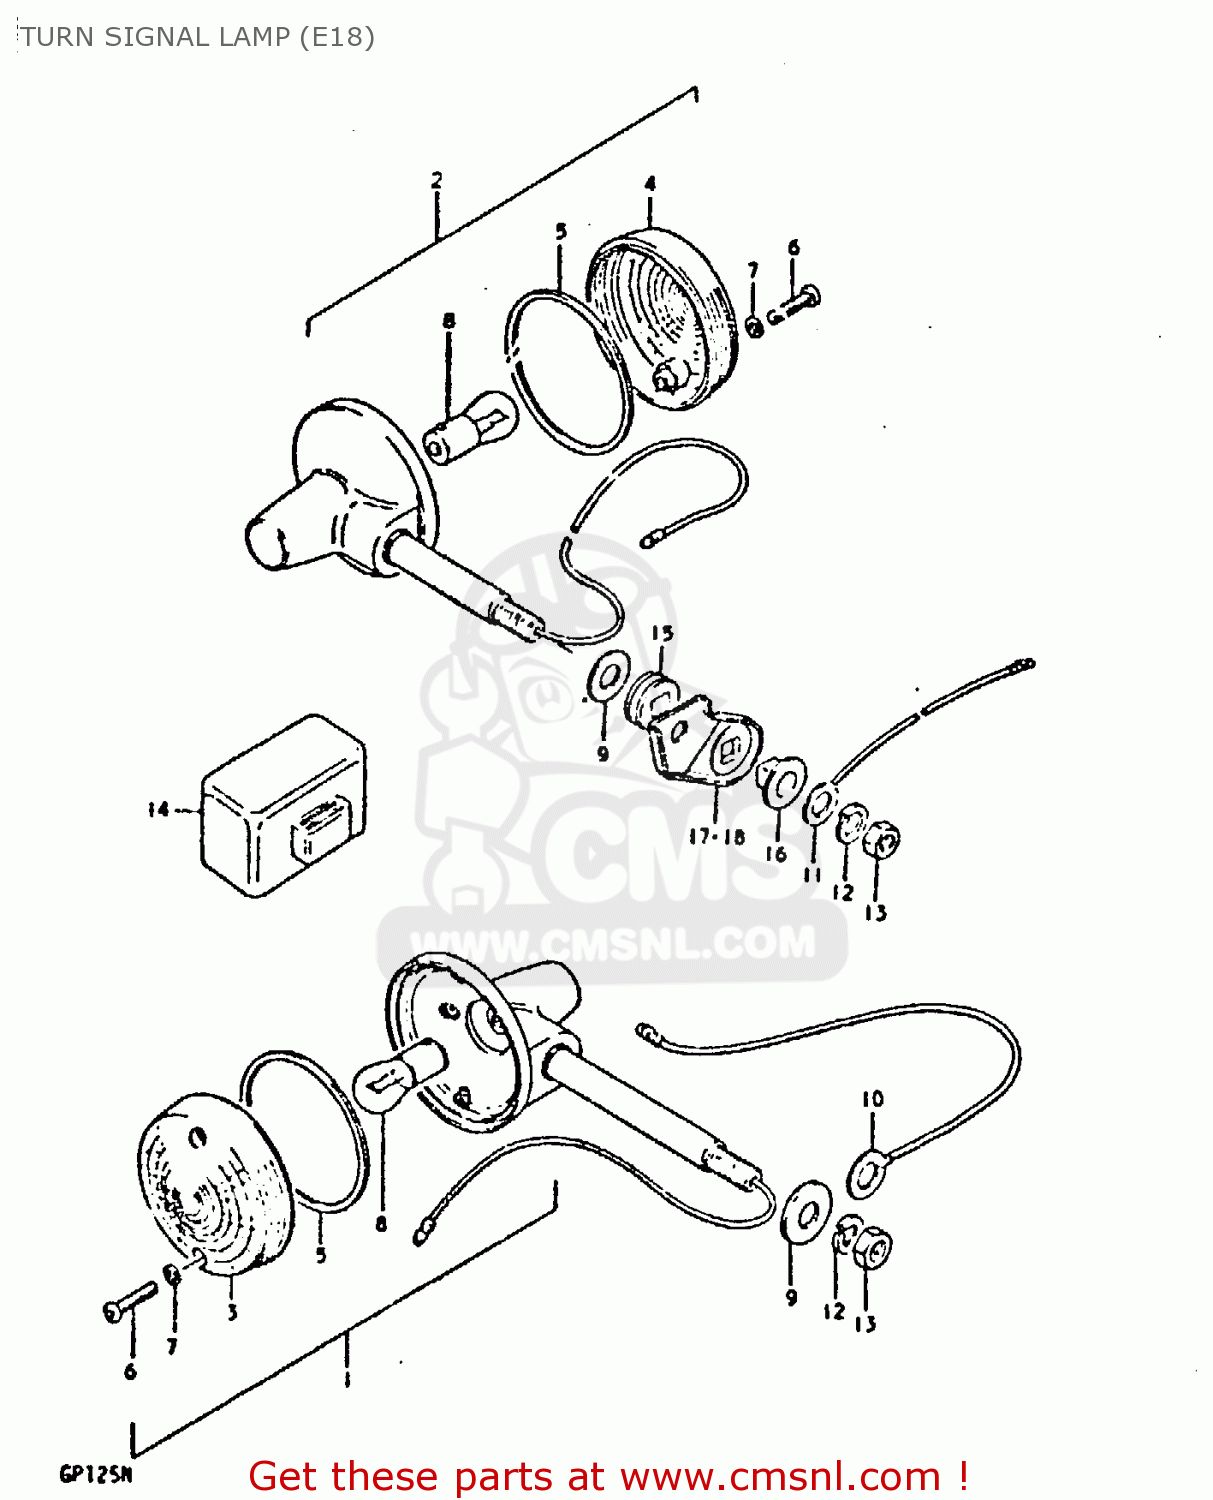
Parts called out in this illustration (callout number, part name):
1	LAMP, FRONT TURN SIGNAL
2	LAMP, REAR TURN SIGNAL
3	LENS
4	LENS
5	GASKET (NAS)
6	SCREW
7	GASKET (NAS)
8	BULB (6V,21W)
9	WASHER (10.5X30X2.3)
14	RELAY, TURN SIGNAL
